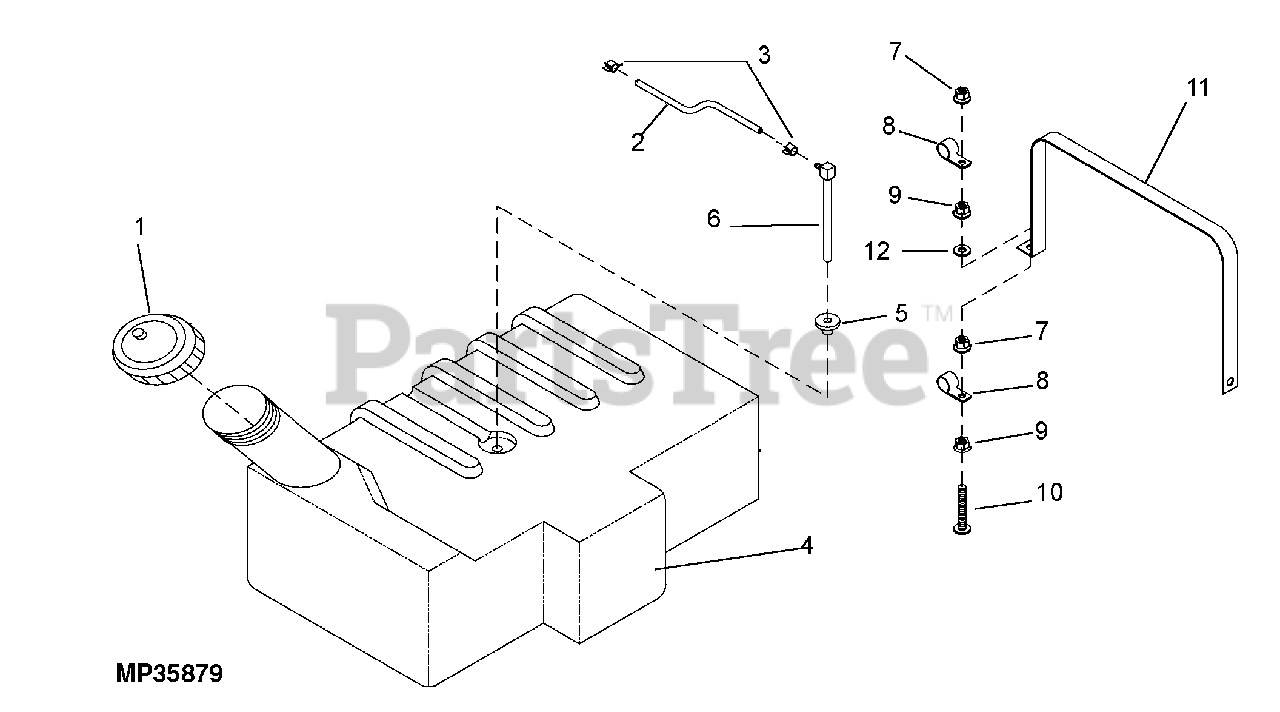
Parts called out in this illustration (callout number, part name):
1	CAP, FUEL S/O
2	HOSE, 1/4" ID LOW PERM FUEL 50
4	TANK, FUEL - 8 GAL
5	OBS, REPLACED BY 181208O
6	PICKUP, FUEL
7	LOCKNUT, 5/16-18 NYLOC Y
8	P-CLIP, .750 INSULATED
9	NUT,5/16-18 UNC-2B HX FLG SRTD
10	BOLT, 5/16-18X2.50 CRG 5 Y
11	STRAP, FUEL TANK
12	WASHER, 5/16 X 3/4 FLAT
